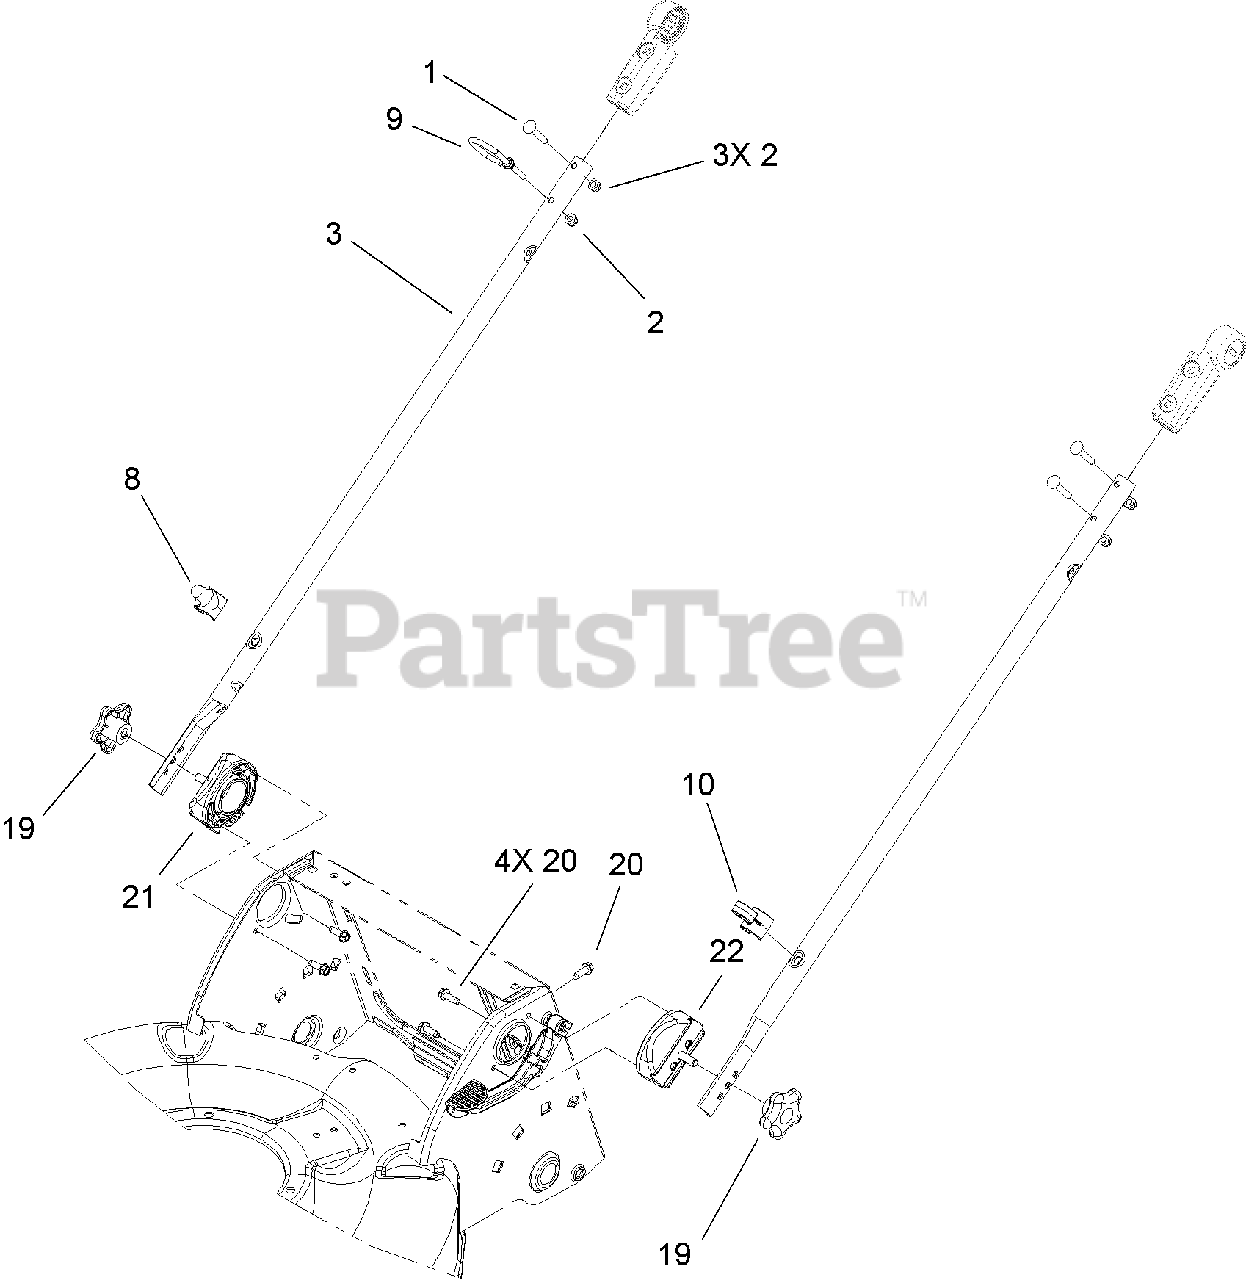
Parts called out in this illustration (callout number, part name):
1	SCREW-CARR
2	NUT-LOCK, NI
8	GUIDE-ROPE, LOWER
9	GUIDE-ROPE, UPPER
10	Guide-Cable
19	KNOB-HANDLE
20	SCREW-HWHTF
21	RH HANDLE MOUNT ASM
22	LH HANDLE MOUNT ASM
